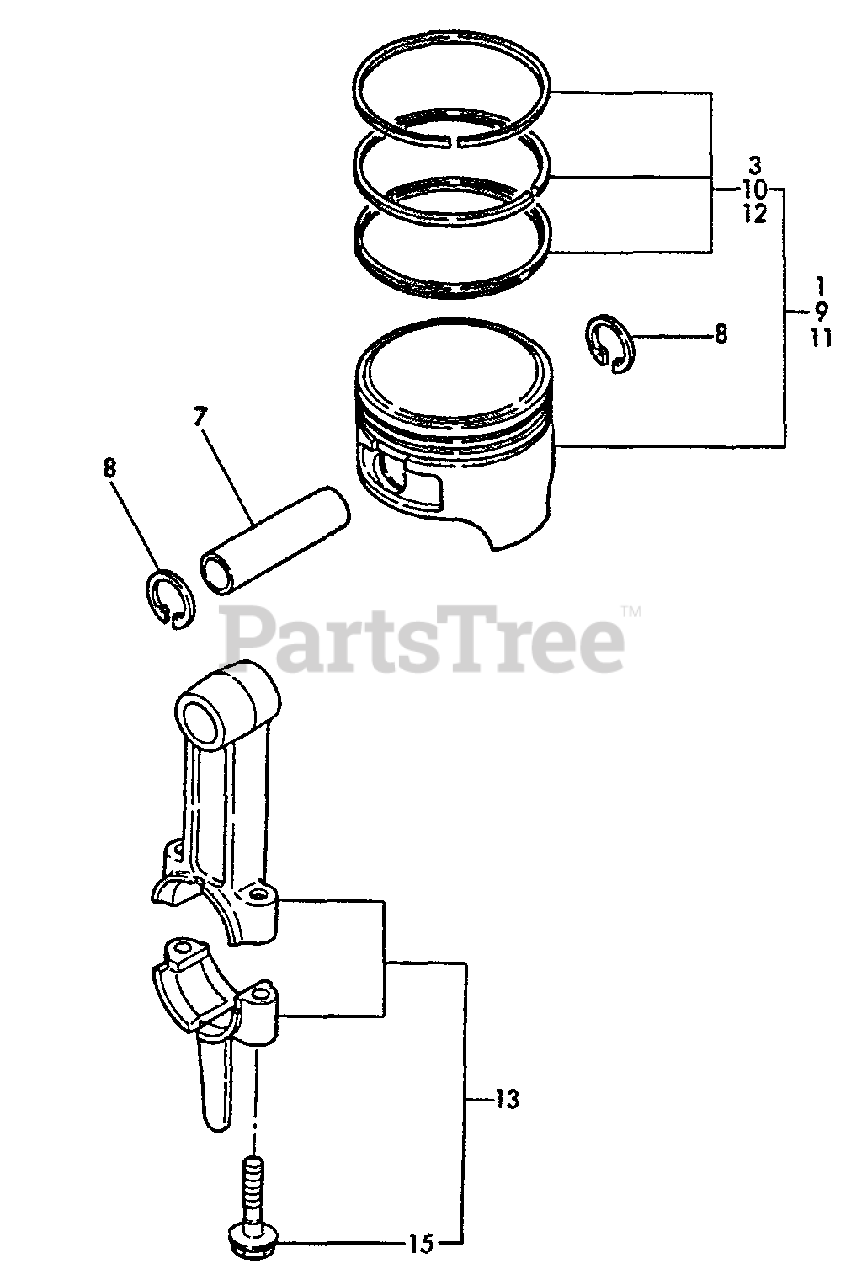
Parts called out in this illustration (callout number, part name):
1	PISTON ASSY
3	PISTON RING ASSY
7	PIN, PISTON
8	RING, RETAINING - 16
9	PISTON ASSY O.S.=0.25
10	RING ASSY O.S.=0.25
11	PISTON ASSY O.S.=0.5
12	RING ASSY O.S.=0.5
13	CONNECTING ROD ASSY
15	BOLT, ROD
